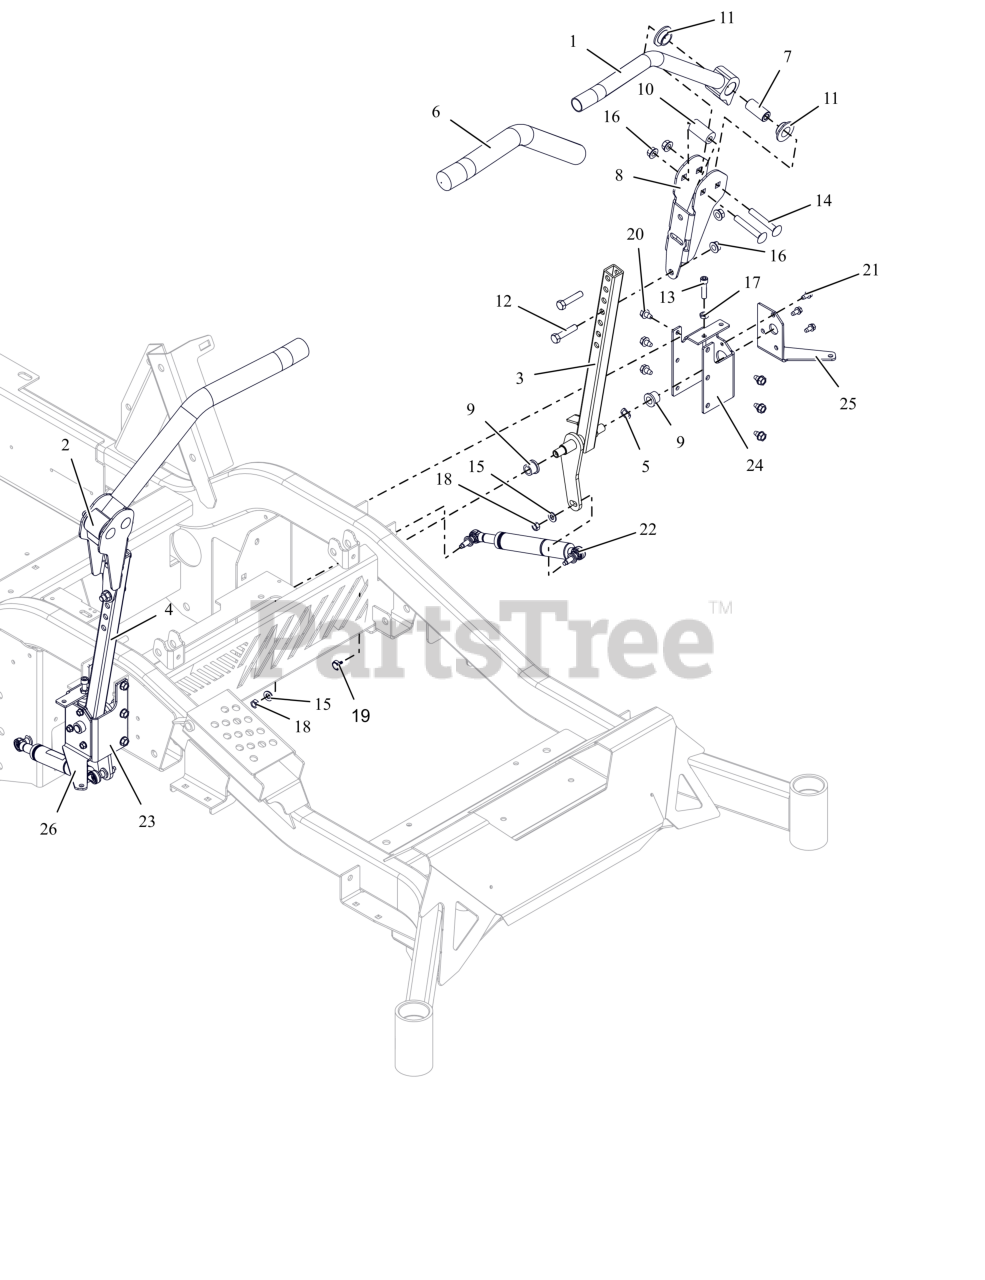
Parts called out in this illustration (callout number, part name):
1	WLDMT, CONTROL HANDLE-LH (BLACK)
2	WLDMT, CONTROL HANDLE-RH (BLACK)
3	WLDMT, STEERING -LH (BLACK)
4	WLDMT, STEERING RH (BLACK)
5	WAVE WASHER .531X.781X.125FH
6	GRIP, HANDLEBAR
7	SPACER, STEERING ARM
8	ADJ UPPER CONTROL ARM BRKT-BLK
9	BSHG, FLG .516X.750X.625X.937
10	BSHG, ECCENTRIC.406X.875X1.625
11	BSHG-FLG .762X1.48X.44 IGLIDER
12	BLT, HEX .38-16X1.75 G5 ZCC
13	BLT, SHCS .312-18X1.25 G8 SS
14	BLT, RHSSN.38-16X2.50 G5 ZCC
15	WSHR, HRDN 0.344X0.688X0.065
16	NUT-LK-CTR-FLG .375-16 GF ZCC
17	NUT-JAM .312-18 G2 ZCC
18	NUT, HEX-JAM CTR-LK M8-1.25 ZCC
19	BOLT, MAGNETIC STEERING SENSOR
20	SCR,TAP .312-18X.50 HWH TR ZCC
21	SCR-TAP .25-20X.50 HWH ZCC
22	DAMPER, NEUTRALIZING
23	WLDMT, STEERING MOUNTING- RH (ORANGE)
24	BRKT, STEERING MOUNTING -LH (ORANGE)
25	BRKT, FRONT FENDER MOUNT-LH (BLACK)
26	BRKT, FRONT FENDER MOUNT-RH (BLACK)
